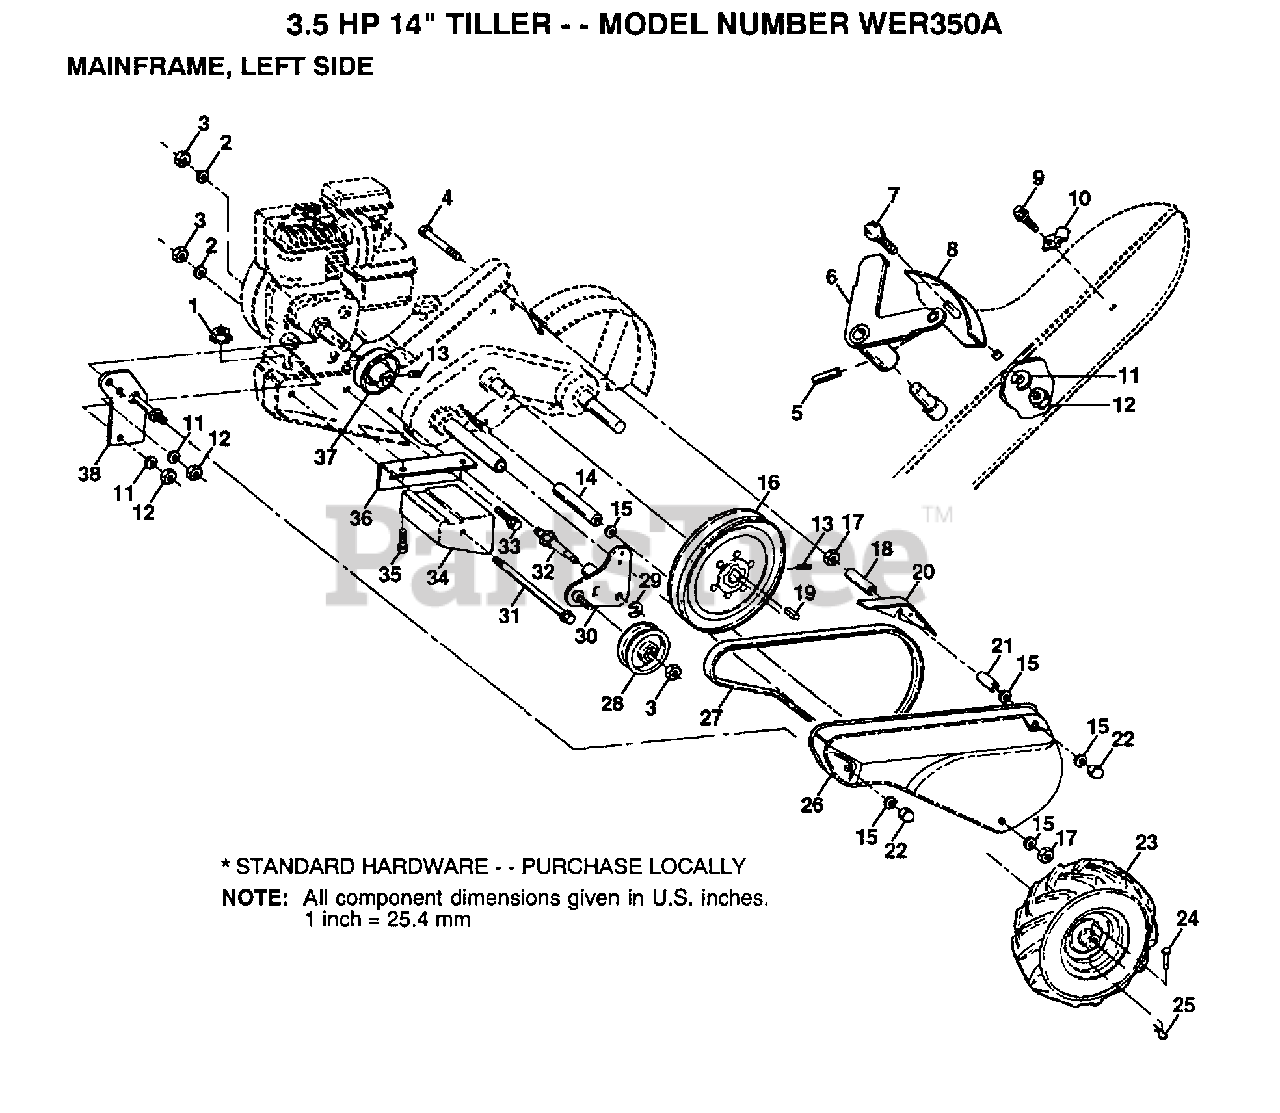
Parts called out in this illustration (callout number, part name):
2	LOCKWASHER
3	NUT.HEX.3/8-16UNC
4	BOLT TI
6	LEVER ASM CRT
7	BOLT
8	PANEL TI
10	CONDIUT CLIP T
11	LOCKWASHER
13	SET SCREW
14	SPACER
15	WASHER
16	"SHEAVE 10"" CRT"
17	NUT.HEX.5/16-18
18	SPACER CRT
19	KEY T
20	GUARD CRT
21	SPLIT SPACER
22	NUT TI
23	TIRE.CHV.13X5.0-6
24	RIVET.DRILL.1.75
25	RETAINER M
26	"GUARD, BELT"
27	BELT-V
28	PULLEY-IDLER TI
29	KLIP RING
31	BOLT CRT
32	SHIFT ARM CRT
33	BOLT
34	COUNTERWEIGHT CRT
35	BOLT.HEX.5/16-1.5
36	BRACKET LH CRT
37	ENGINE SHEAVE
38	BELT GUARD BRKT
